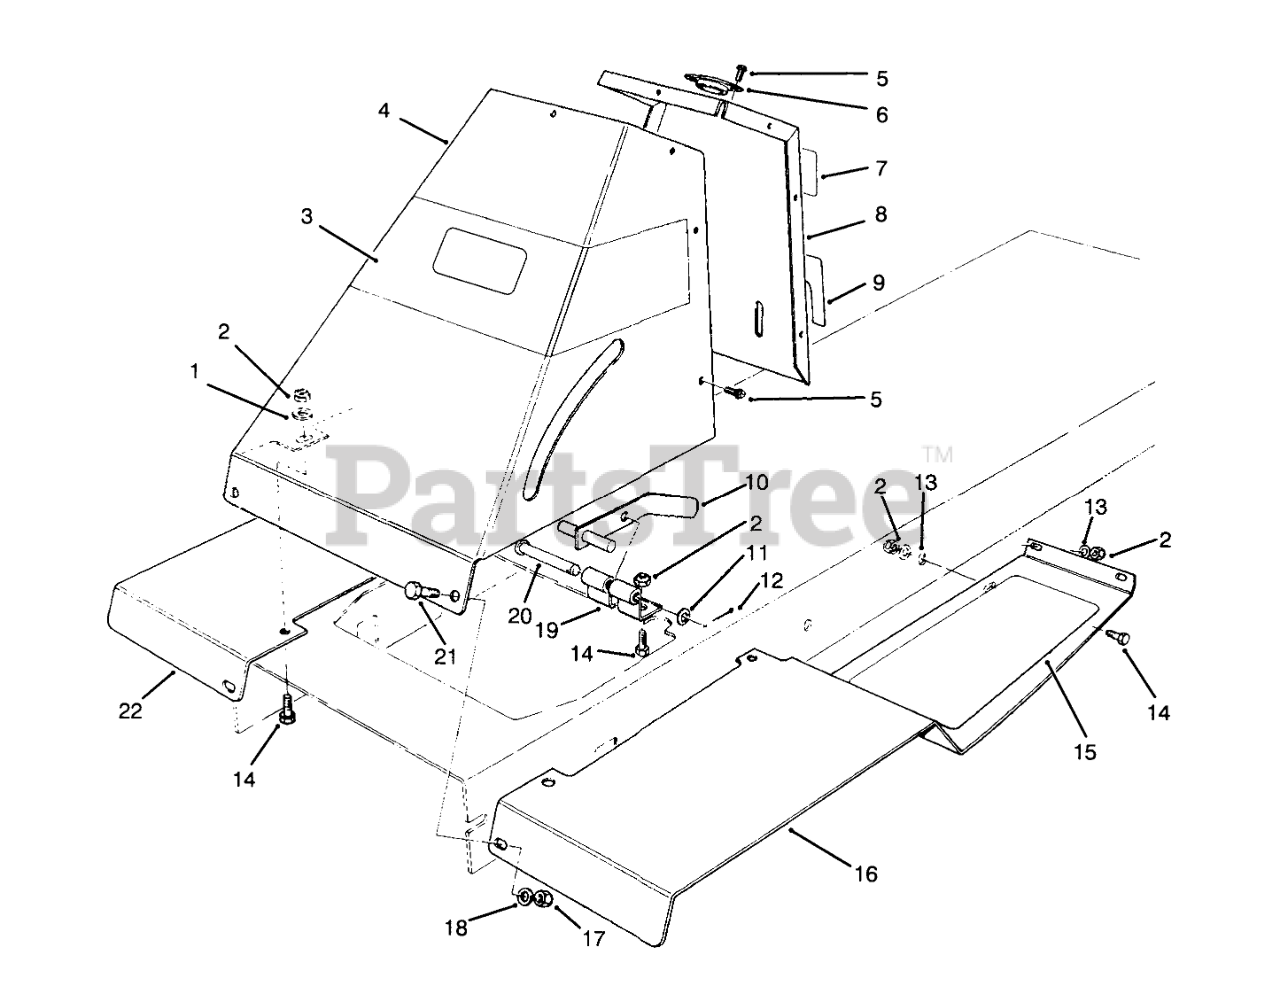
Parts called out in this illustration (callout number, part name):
1	WASHER-FLAT
2	NUT-LOCK, NI
3	DECAL - STEERING SUPT
4	Tower-Front
5	SCREW-HWHTF
6	GUIDE-STRG SHAFT
7	DECAL-DANGER
8	Tower-Rear
9	PARK BRAKE DECAL
10	PARKING BRAKE WA B
11	WASHER-FLAT
12	PIN-COTTER
13	WASHER-PLAIN
14	SCREW-HH
15	TREAD-L.H. FOOT
16	Footrest-LH
17	NUT-LOCK, NI
18	WASHER-FLAT
19	Bracket-Parking Brake
20	PIN-CLEVIS
21	SCREW-HH
22	Footrest-RH.
